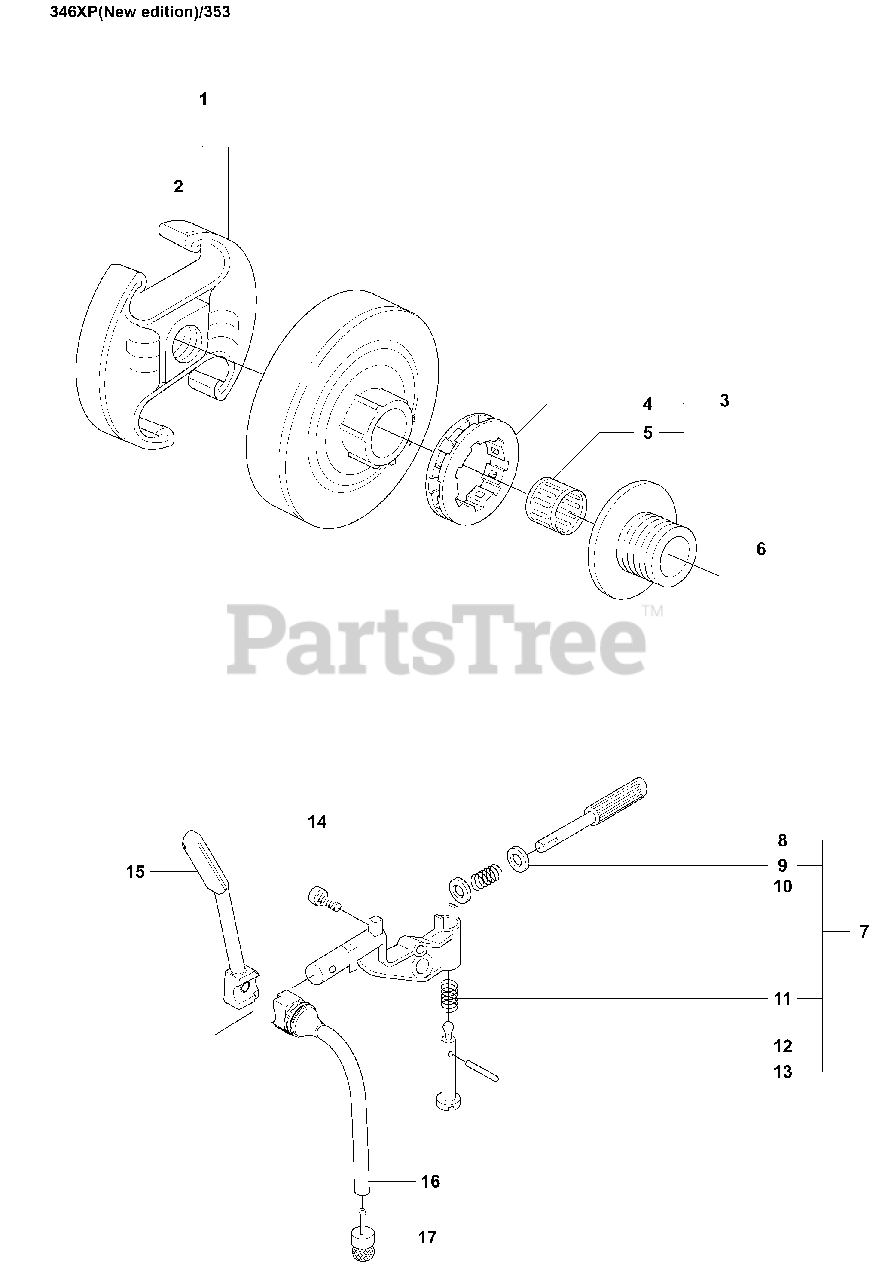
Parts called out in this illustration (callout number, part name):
2	SPRING
3	%CLUTCH DRUM
4	RIM SPROCKET 7T .325
5	NEEDLE BEARING
6	%PINION
7	OIL PUMP COMPLETE
8	%PUMP PISTON
15	OIL PRESSURE HOSE
16	RP HOSE
17	OIL PLUMMET
